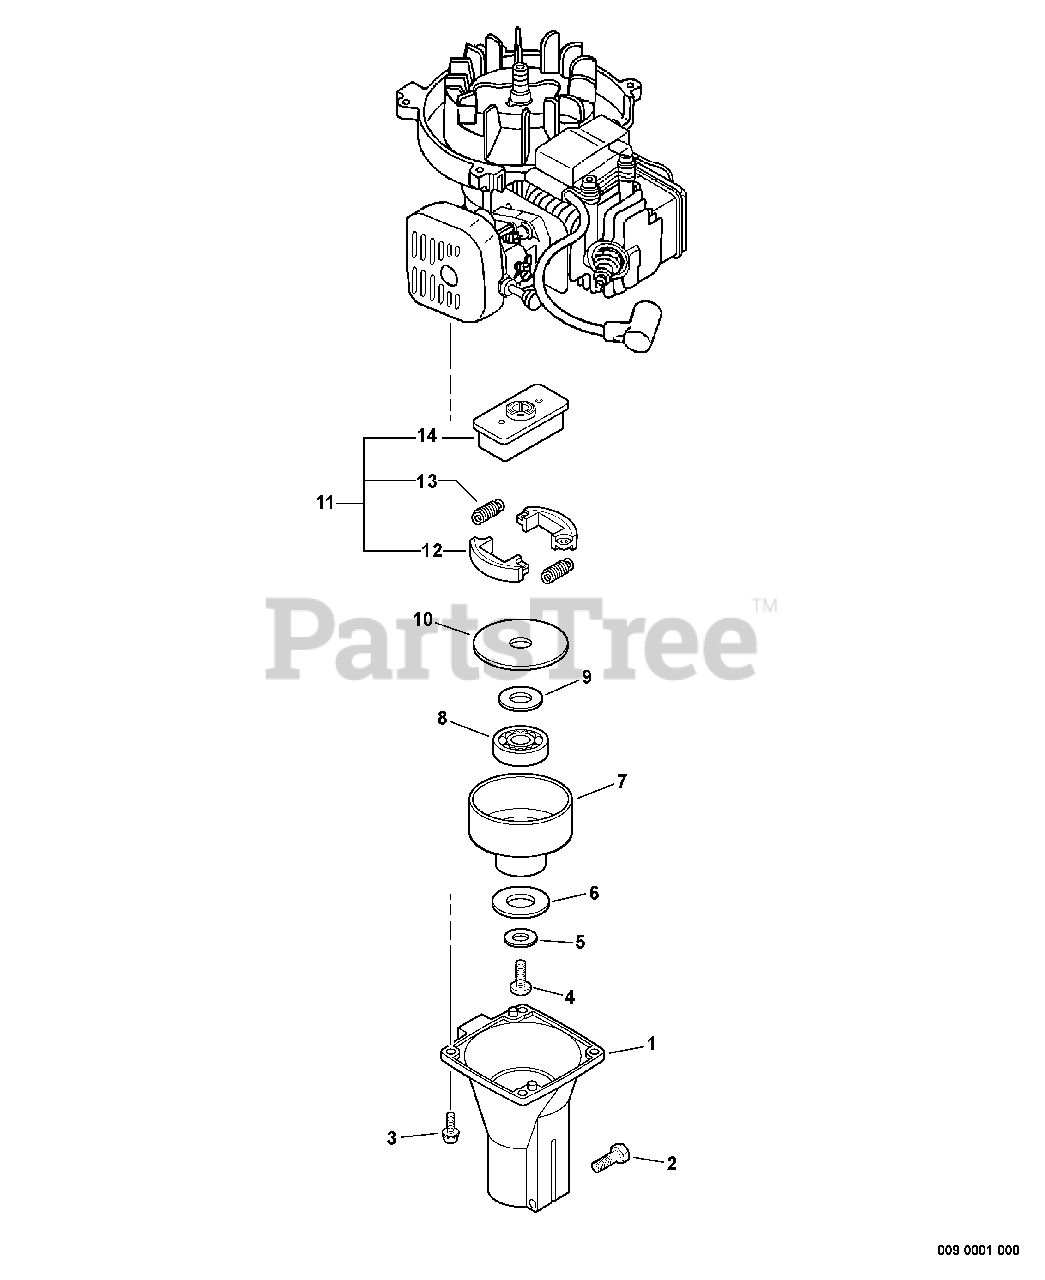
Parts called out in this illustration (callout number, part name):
1	CASE, CLUTCH
2	BOLT 5
3	SCREW 4×14
4	SCREW 6×12
5	WASHER, CLUTCH
7	DRUM, CLUTCH
8	BEARING, BALL 6000-2RLB
9	WASHER 10.5×18×1.6
10	PLATE, CLUTCH
11	CLUTCH ASSY
12	SHOE, CLUTCH
13	SPRING, CLUTCH
14	HUB, CLUTCH
